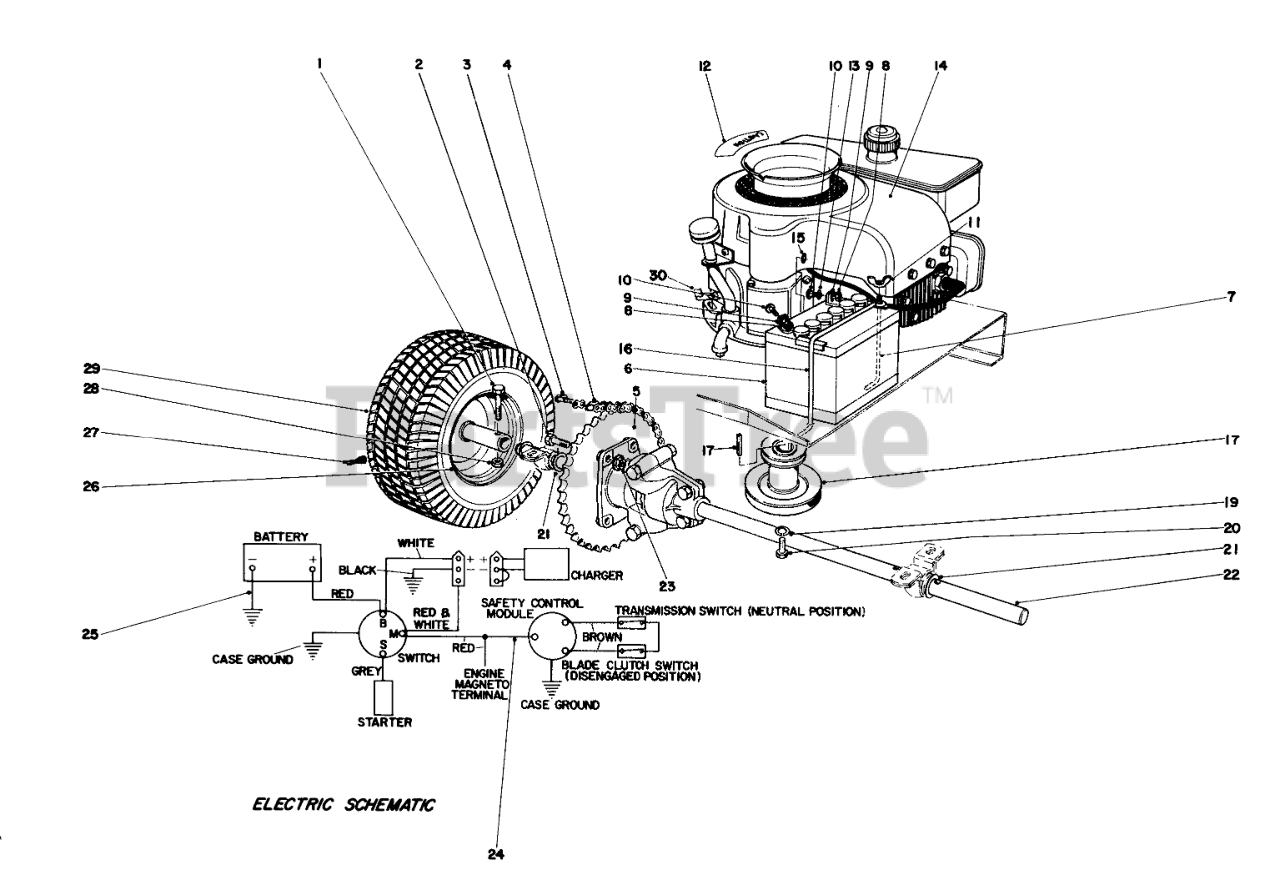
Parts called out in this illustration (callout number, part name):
1	SCREW-HH
2	SCREW-HH
3	LINK-CONNECTING
4	Chain Roller (Incl. Ref. #3)
5	Sprocket
6	BATTERY
7	ROD-SUPPORT, BATTERY
8	NUT-HEX
9	WASHER-LOCK
10	SCREW-HH
11	Wing Nut
12	Decal
13	WASHER-FLAT
14	Engine
15	WASHER-LOCK/EXT
16	Battery Clamp
18	Engine Pulley
19	WASHER-LOCK
20	SCREW-HH
21	WASHER
22	Differential
23	NUT-LOCK, CONE
24	Wiring Harness
25	ENG-GROUND WIRE ASM
27	STEM-VALVE
28	NUT-LOCK, CONE
29	Tire
